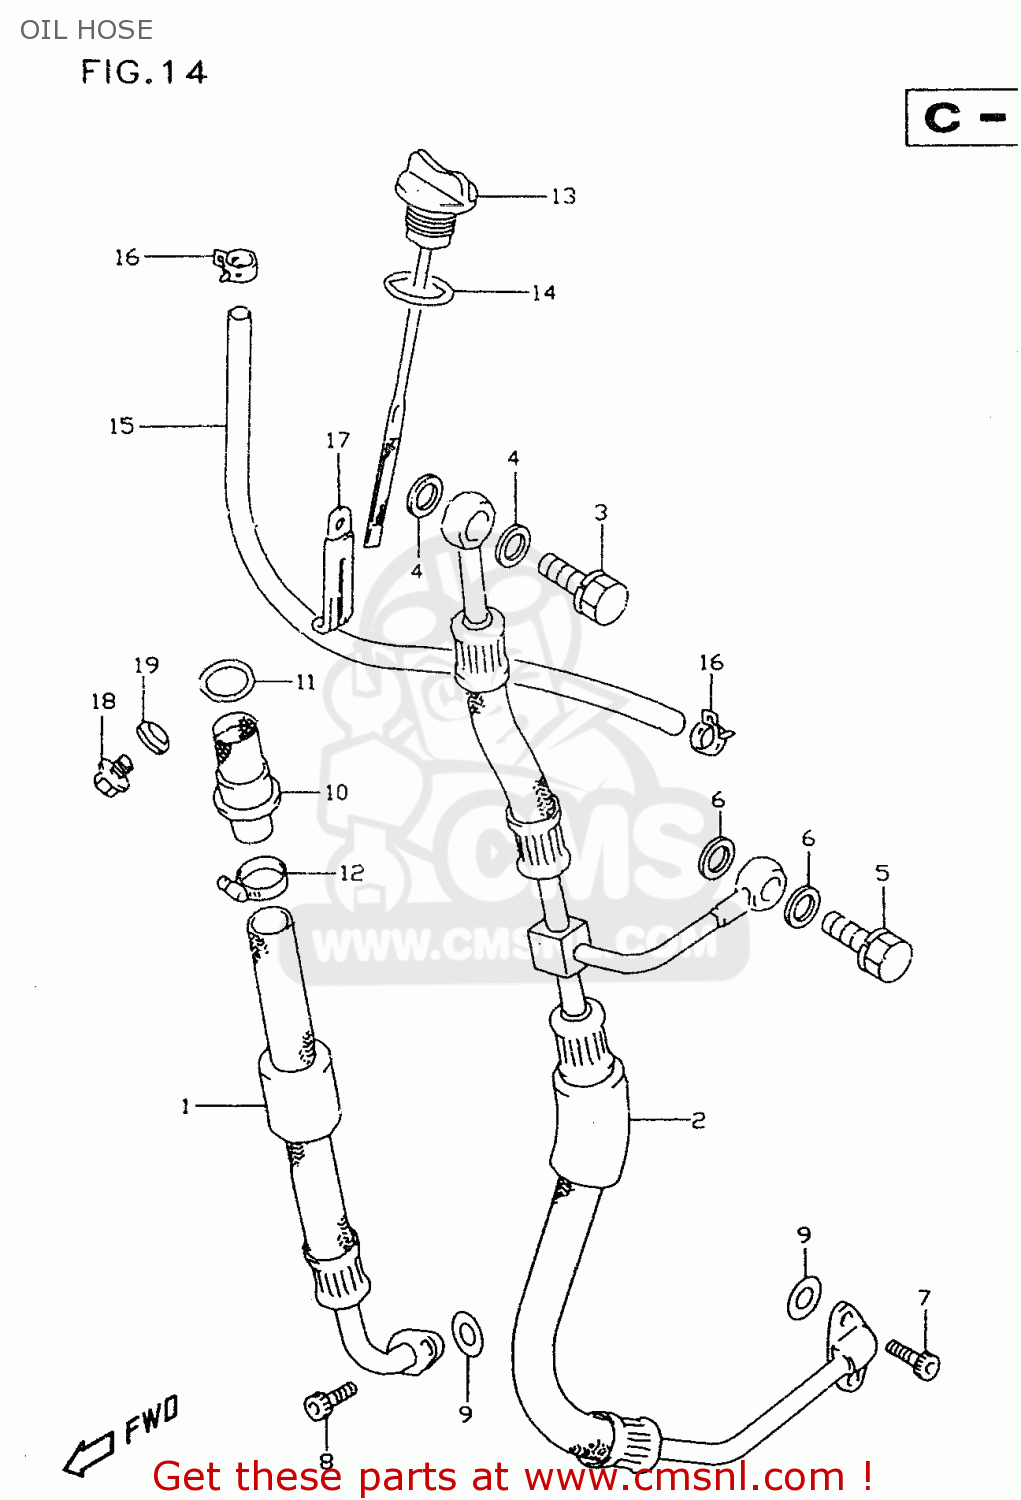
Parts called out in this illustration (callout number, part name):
1	HOSE,OIL TANK INLET
2	HOSE,OIL TANK
3	BOLT UNION
4	GASKET(16X22X2) (NAS)
5	BOLT UNION
6	GASKET(12X17X1) (NAS)
7	BOLT,OIL FILLE
8	BOLT,CRKCASE,R
9	O RING(D:2.4,ID:12.3)
10	STRAINER,FRAME HEAD UNDER
11	O RING(D:3.1,ID:22.7)
12	CLAMP
13	GAUGE ASSY,OIL LEVEL
14	O RING(D:3.1,ID:16.8)
15	HOSE,OIL OVER FLOW
16	CLIP
17	CLAMP(L:55)
18	PLUG(10X12)
19	GASKET(10X14X3.6) (NAS)
